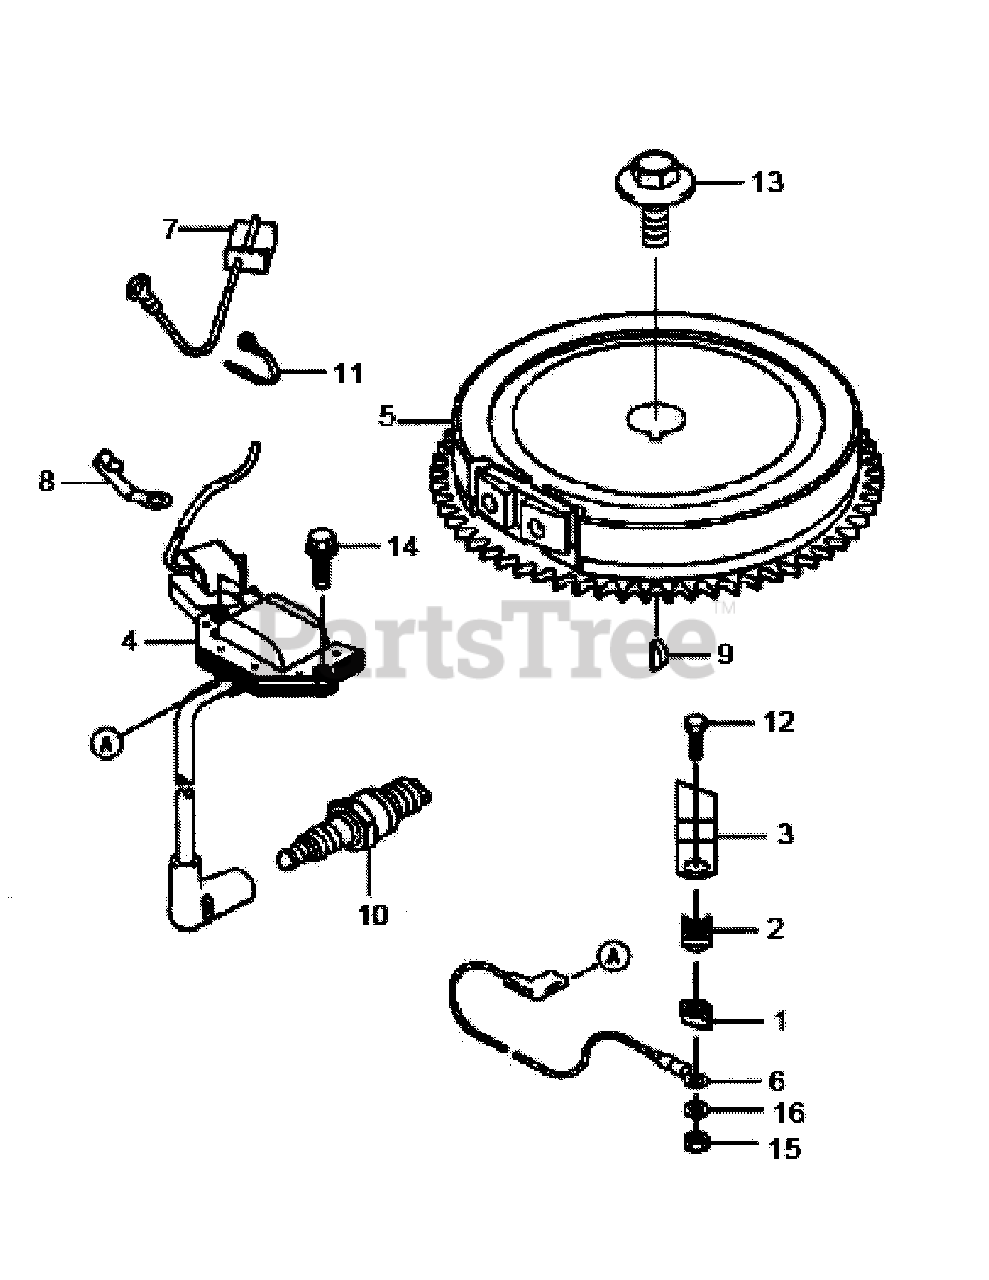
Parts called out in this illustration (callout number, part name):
4	Ignition Coil Assy.
10	Spark Plug
14	Flanged Bolt
15	Hex Nut
16	Plain Washer
